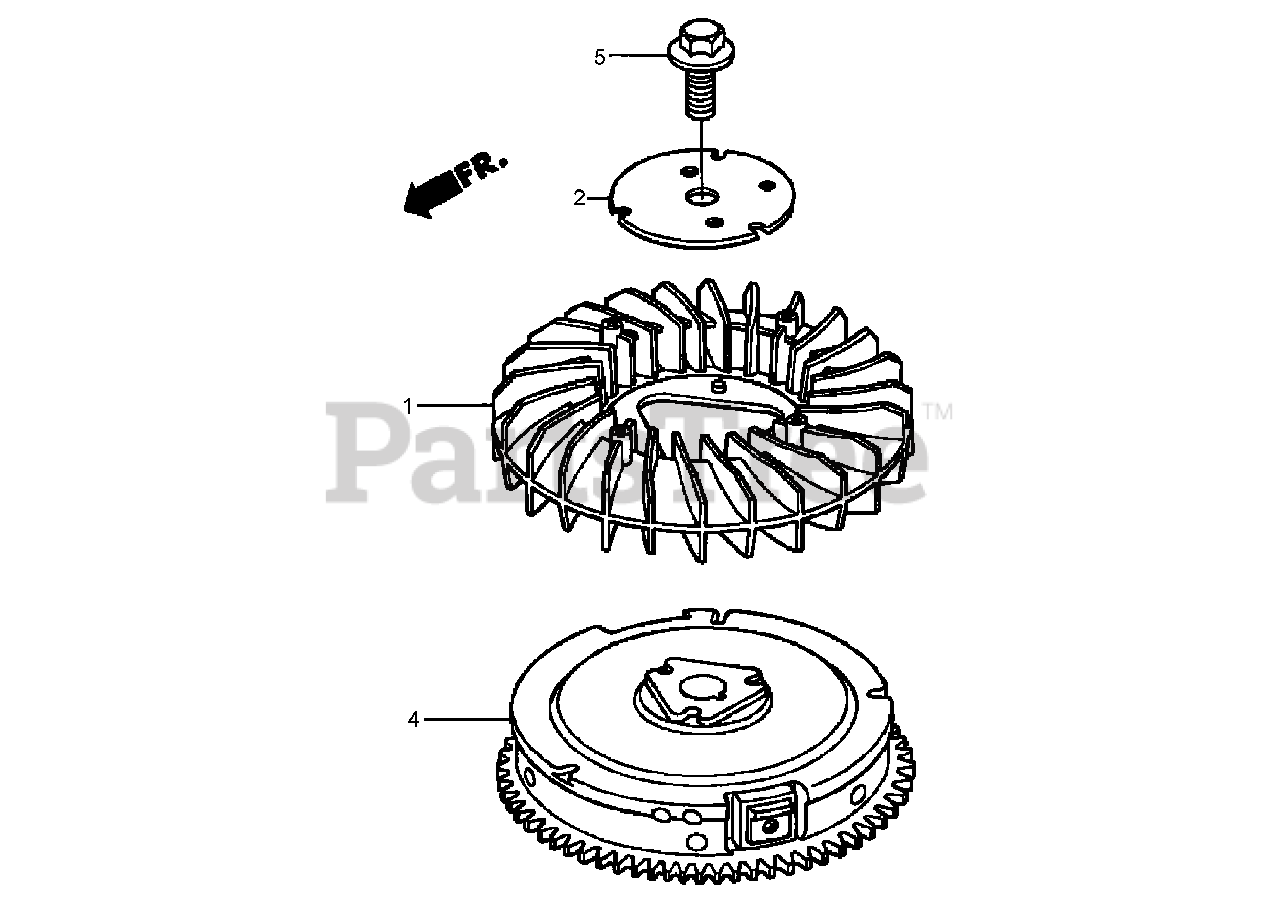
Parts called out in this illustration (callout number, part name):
1	FAN-COOLING
2	PLATE-SETTING, COOLING FAN
4	FLYWHEEL (6P)
5	BOLT-FLANGE (16X35)
